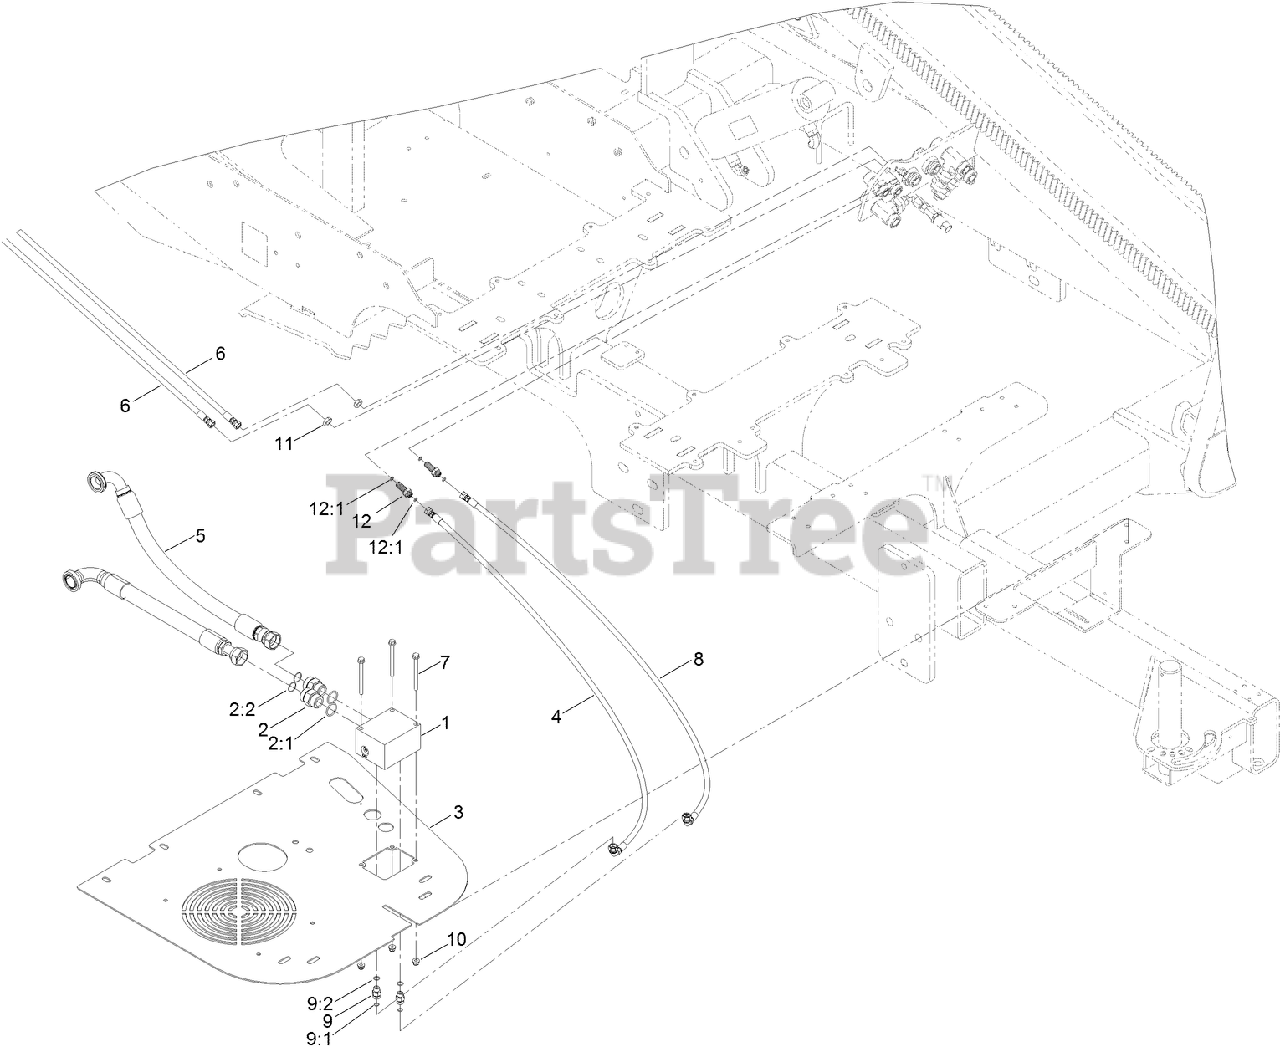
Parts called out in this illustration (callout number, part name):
1	MANIFOLD-VALVE
2	FITTING-STRAIGHT
2:1	O-RING
2:2	O-RING
3	PLATE-BULKHEAD
4	HYD HOSE ASM
5	HYD HOSE ASM
6	HYD HOSE ASM
7	SCREW-HHF
8	HYD HOSE ASM
9	FITTING-STRAIGHT
9:1	O-RING
9:2	O-RING
10	NUT-LOCK, HHF
11	NUT-LOCK
12	UNION-BULKHEAD
12:1	O-RING
